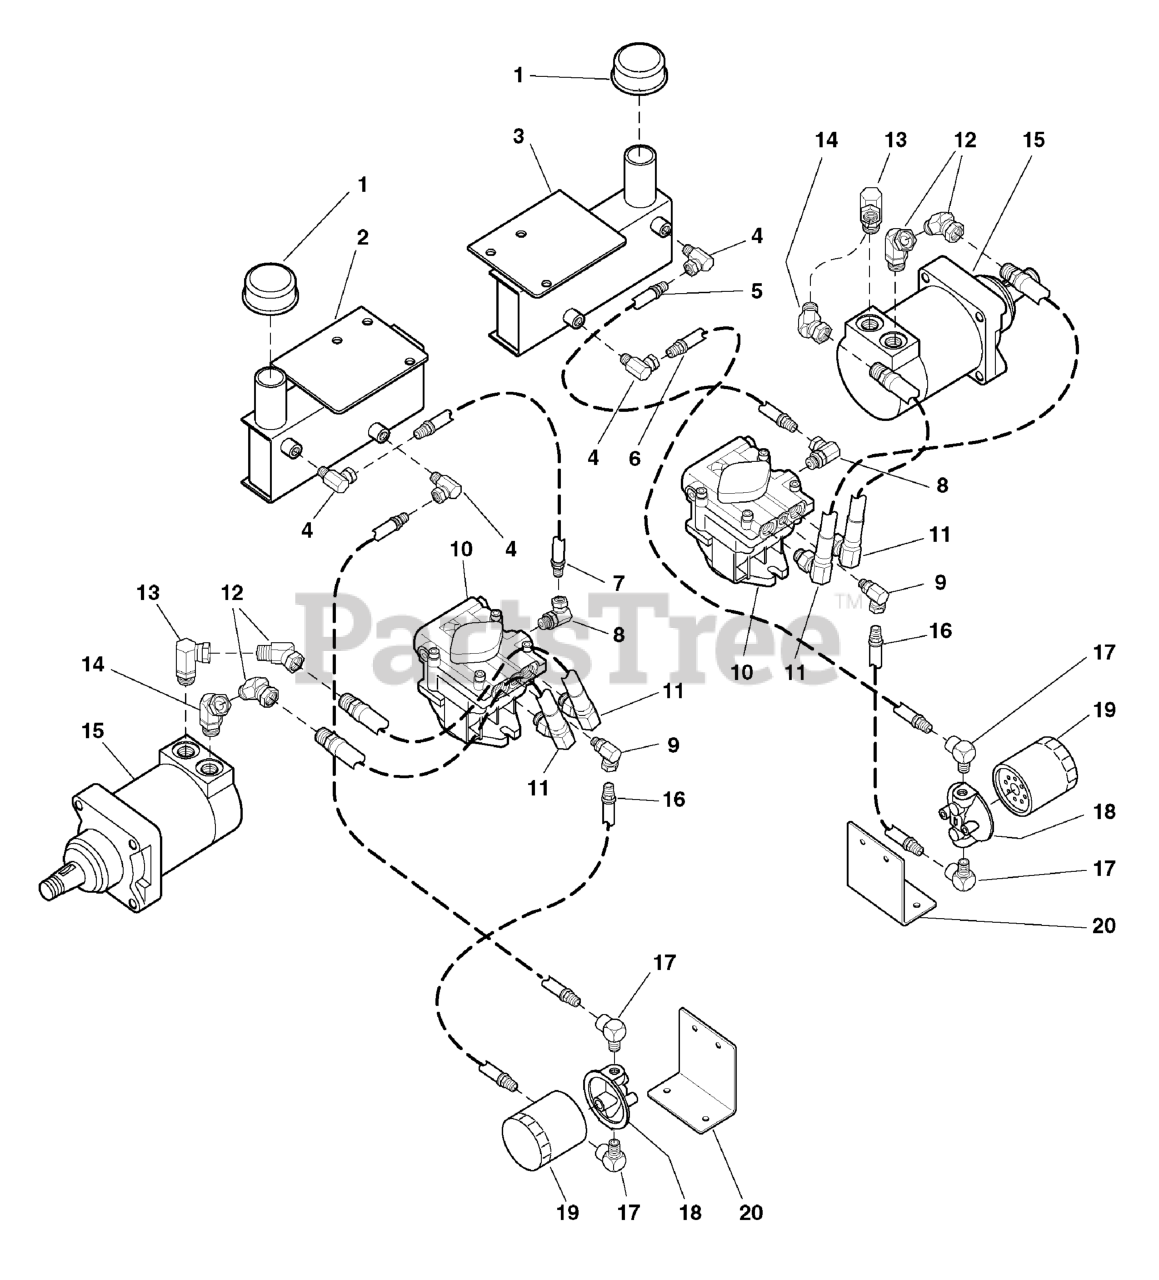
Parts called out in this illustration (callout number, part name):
1	BREATHER
2	HYDRO TANK, LH
3	HYDRO TANK, RH
4	FITTING, 1/4" NPT 90 Degree Swivel
5	HOSE ASSEMBLY-24"
6	HOSE ASSEMBLY-13"
7	HOSE ASSEMBLY-14"
8	FITTING, O-Ring, 90 Deg. Swivel
9	FITTING, 7/16" O-Ring 90 Degree Swivel
10	HYDRAULIC PUMP
12	FITTING, 1/2 NPT, 45 Deg. Swivel
13	FITTING, O-Ring, 90 Deg. Swivel
14	FITTING, 7/8" O-Ring 45 Degree Swivel
15	HYDRAULIC WHEEL MOTOR
15	KEY
15	NUT & COTTER PIN
16	HOSE ASSEMBLY-11"
17	FITTING, 1/4 NPT, 90 Deg.
18	FILTER HEAD
19	FILTER
20	MOUNT, Filter Head
